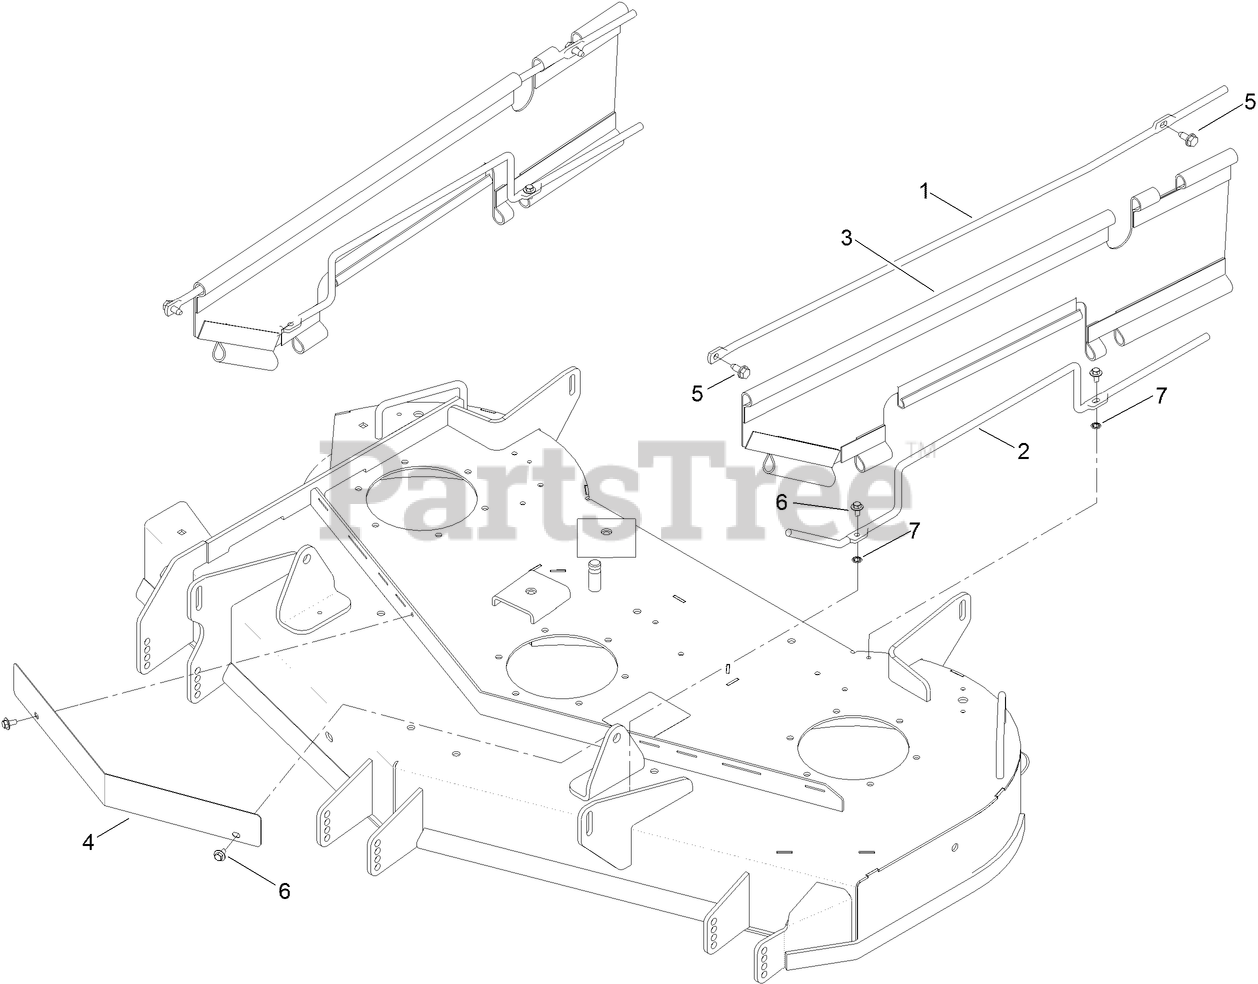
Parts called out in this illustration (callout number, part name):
1	ROD SUPPORT, UPPER
2	ROD SUPPORT, LOWER
3	GUARD-SIDE
4	SHIELD-FRONT
5	SCREW-HWHTF
6	SCREW-HHFTF
7	NUT-RETAINING
